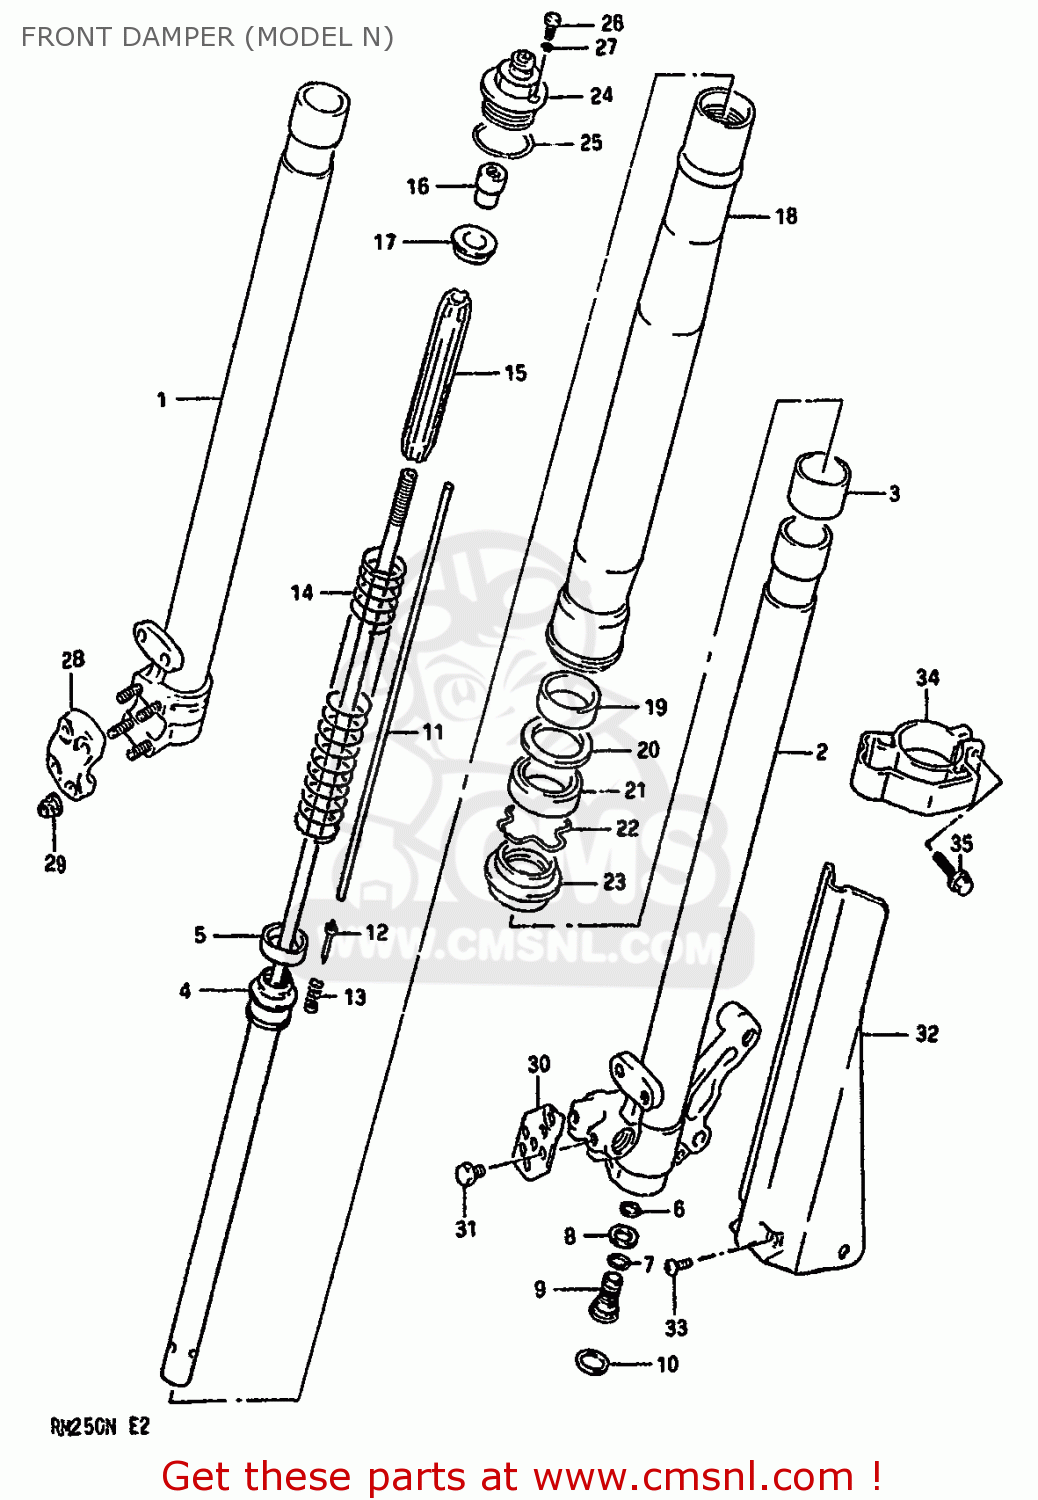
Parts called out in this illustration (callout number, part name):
1	TUBE,INNER,R
2	TUBE,INNER,LEFT
3	BUSH,SLIDE
4	DAMPER
5	RING,PISTON
6	O RING,CTR BOLT UPR
7	O RING,CTR BOLT
8	GASKET (NAS)
9	BOLT,CENTER
10	RING,CTR BOLT STOPPER
11	ROD,PUSH
12	NEEDLE
13	SPRING,PUSH RO
14	SPRING,MAIN
15	GUIDE,SPRING
16	NUT,ROD
17	SEAT,SPRING UPR
18	TUBE,OUTER
19	BUSH,GUIDE
20	SPACER,SEAL
21	OIL SEAL,FRONT FORK
22	RING,OIL SEAL STOPPER
23	SEAL,DUST
24	BOLT,FORK
25	O RING
26	BOLT,PLUG
27	O RING, PLUG
28	HOLDER,AXLE,R
29	NUT
30	GUIDE,HOSE,L
31	BOLT, HOSE GUIDE
32	PROTECTOR,FORK RH
33	BOLT,PROTECTOR(6X10)
34	GUIDE,FORK PROTECTOR
35	BOLT,PROTECTOR GUIDE
36	GUIDE,FORK PROTECTOR,R
37	BOLT,PROTECTOR GUIDE
